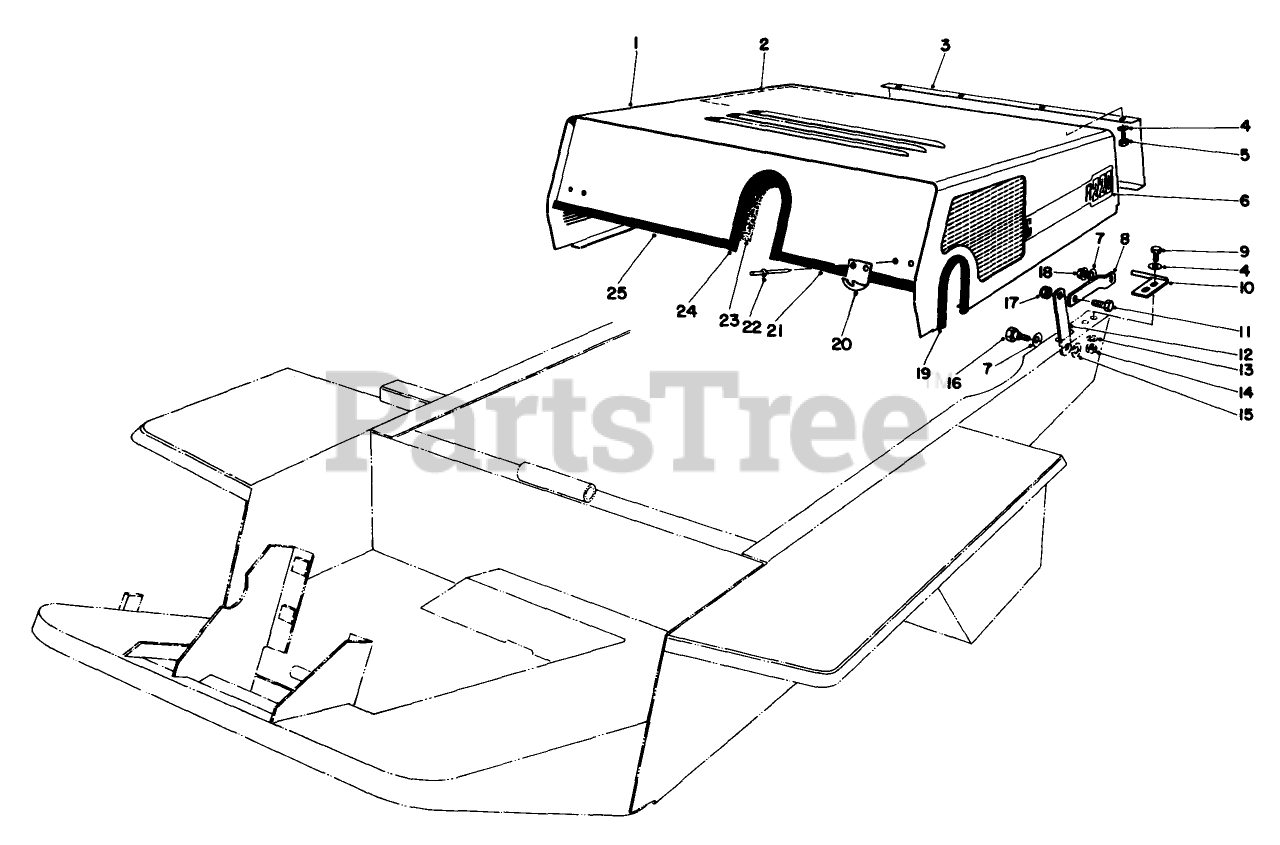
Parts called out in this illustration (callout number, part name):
1	HOOD IN CARTON
2	REAR HOOD FOAM STRIP
3	Grille-Rear Panel
4	WASHER-FLAT
5	Screw
6	GM 220 DECAL
7	WASHER-SPRING
8	Link Hood
9	SCREW-HH
10	PivotPin L.H.
11	SCREW-HH
12	Tie Hood
13	WASHER-LOCK
14	NUT-HEX
15	WASHER-FLAT
16	SCREW-SHOULDER
17	NUT-HEX
18	NUT-HF
19	HOOD TRIM
20	KEEPER
21	HOOD TRIM
22	NUT-LOCK, NI
23	FRT HOOD FOAM STRIP
24	HOOD TRIM
25	TRIM-HOOD
